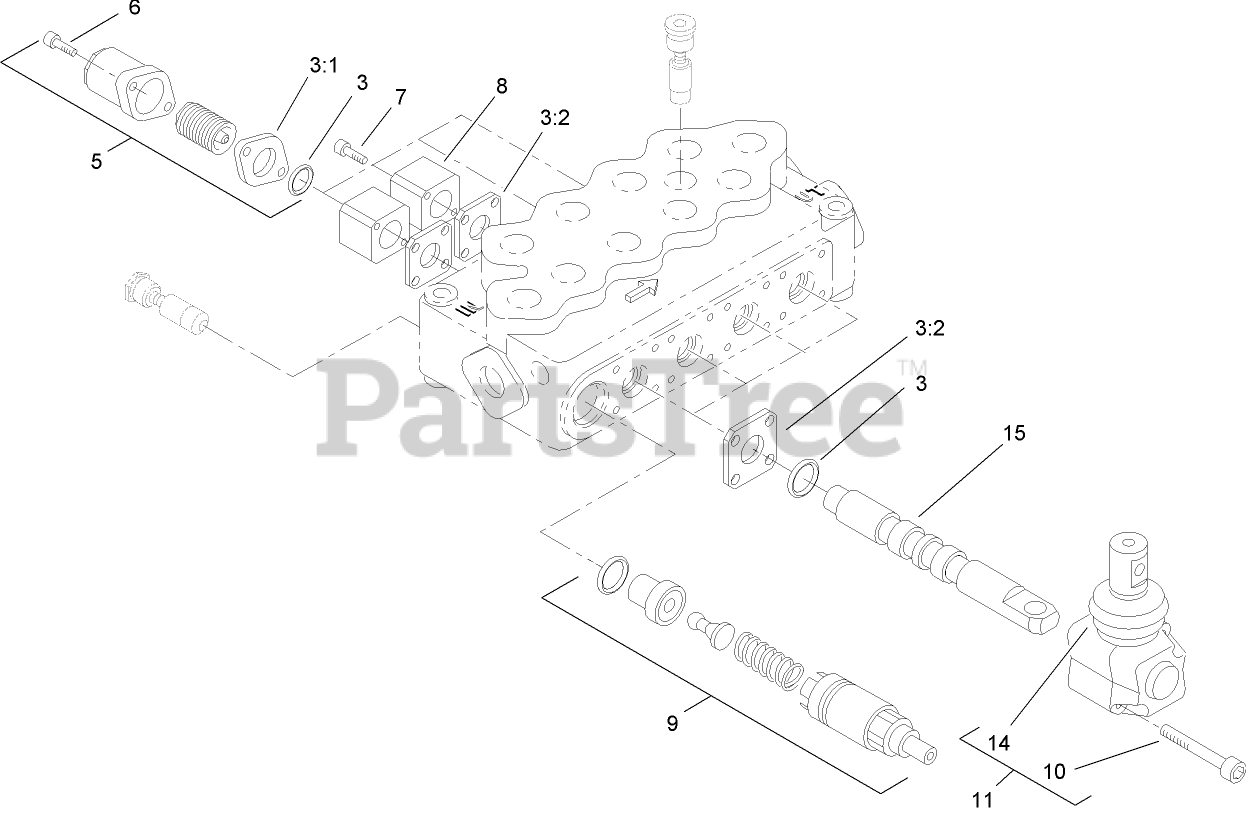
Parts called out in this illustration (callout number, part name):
3	SEAL KIT
3:1	GASKET
3:2	GASKET
5	STANDARD SPRING KIT
5	HIGH FORCE SPRING KIT
6	SCREW-CAP, END
8	BLOCK-MOUNT, SWITCH
9	VALVE-RELIEF
11	OPERATOR ASM
15	SPOOL-VALVE
